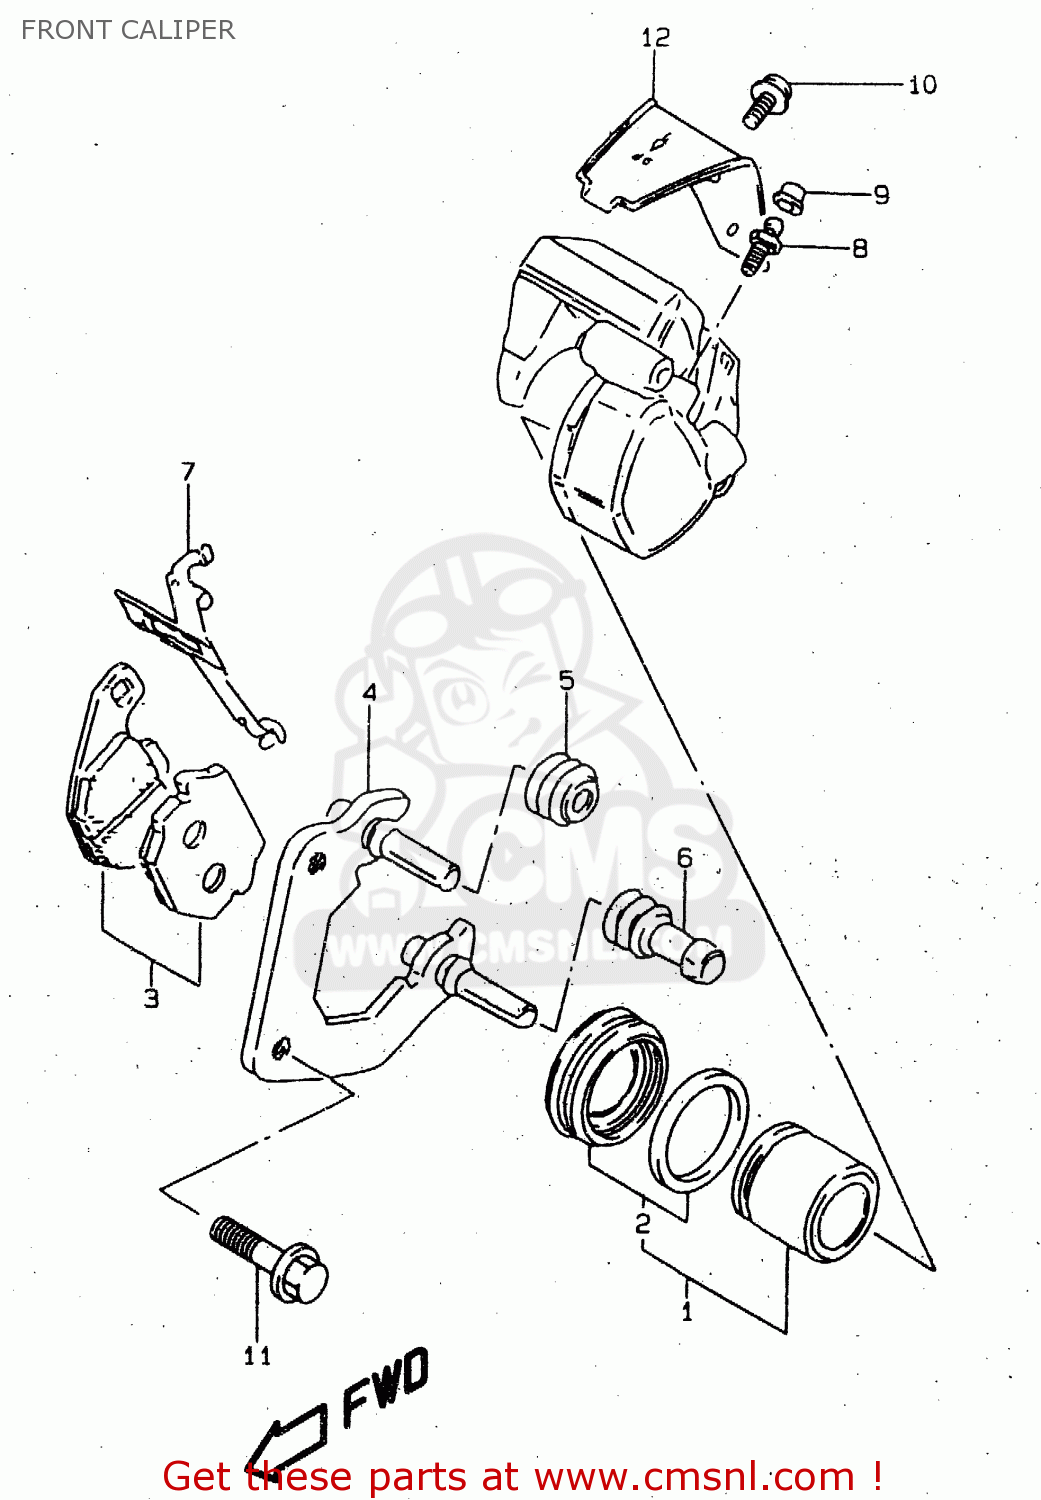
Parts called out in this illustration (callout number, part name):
1	PISTON SET
2	SEAL SET,PISTON
3	PAD SET (NAS)
4	CARRIER,L
5	BOOT,AXLE
6	INSULATOR,AXLE
7	SPRING,PAD
8	BLEEDER
9	CAP,BLEEDER PLUG
10	SCREW
11	BOLT
12	PROTECTOR,CALIPER
